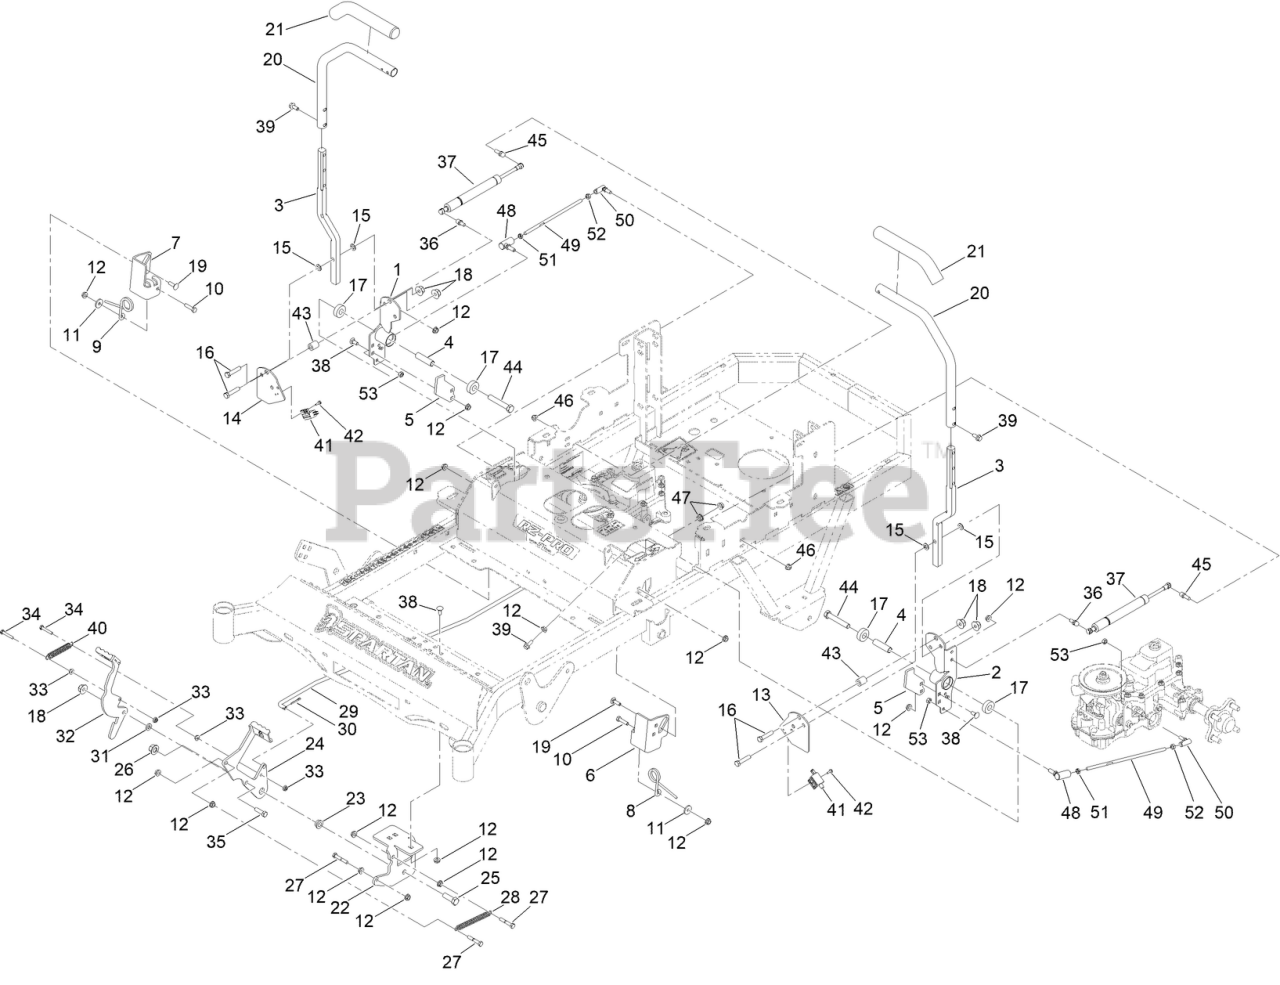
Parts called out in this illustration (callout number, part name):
1	MOTION CONTROL BRKT
2	MOTION CONTROL BRKT
3	HEIGHT ADJUSTABLE CONTROL ARM
4	MWR DRIVE ARM HUB / DECK LIFT ARM SPACER
5	REVERSE DETENT KICK PLATE
6	REVERSE DENTENT SPRING BASE (LH)
7	REVERSE DENTENT SPRING BASE (RH)
8	SPRING- LT REVERSE DETENT
9	SPRING-TORSION
10	SCREW-HH
11	STRIKER POST FENDER WASHER
12	NUT-HF
13	LT CONTROL ARM LIMIT SWITCH PLATE PAINT
14	RT CONTROL ARM LIMIT SWITCH PLATE PAINT
15	3/8 X 3/4 BRONZE WASHER
16	3/8-16 X 1-3/4 HEX C/S GR 2 ZINC
17	5/8IN ID X 1-3/8IN OD X 7/16IN THK BRG
18	3/8-16 NYLON INSERT FLANGE L/NUT YZ
19	5/16-18 X 1 CARRIAGE BOLT GR 8 YZ
20	MOWER DRIVE HANDLE TUBE ABC
21	CONTROL ARM HANDLE GRIP
22	MWR FRAME BRAKE MTG BRKT PAINT
23	1/2IN ID X 3/4IN OD X 3/8IN FLANGE BUSH
24	MWR BRAKE LOCK LEVER ASSY PAINTED
25	SCREW-HH
26	NUT-LOCK
28	2020 MWR BRAKE PEDAL TENSION SPRING
29	MWR BRAKE LINKAGE
30	PIN-COTTER
31	3/8 ID X 3/4 OD X .125 THK BRONZE WASHER
32	MWR BRAKE UNLOCK LEVER ASSY PAINTED
33	1/4-20 HEX FLANGE NUT
34	1/4-20 X 1-1/4 HEX C/S GR 2 ZINC
35	SCREW-HH
36	5/16-18X1.286 DAMPER BALL STUD (.562 TL)
37	CONTROL ARM DAMPER
38	BOLT-CARR
39	SCREW-HHF
40	MWR BRAKE PEDAL RELEASE SPRING
41	NO PLUNGER LIMIT SWITCH
42	8-32 X 1/2 IND. HWH SLOT TYPE F TCS ZINC
43	MWR DRIVE ARM SPACER
44	1/2-13 X 3 HEX C/S GR 5 ZINC W/LOCTITE
45	5/16-18X1.286 DAMPER BALL STUD (.562 TL)
46	NUT-HF, NI
47	NUT-HHF, WHIZ
48	CONTROL ARM ROD END LT
49	MWR DRIVE ARM ROD TTQ 400 + 300 TRANS
50	BALLJOINT-RH (W/GROMMET)
51	NUT-JAM
53	5/16-24 NYL INS L/N GR.8 ZC/YEL
